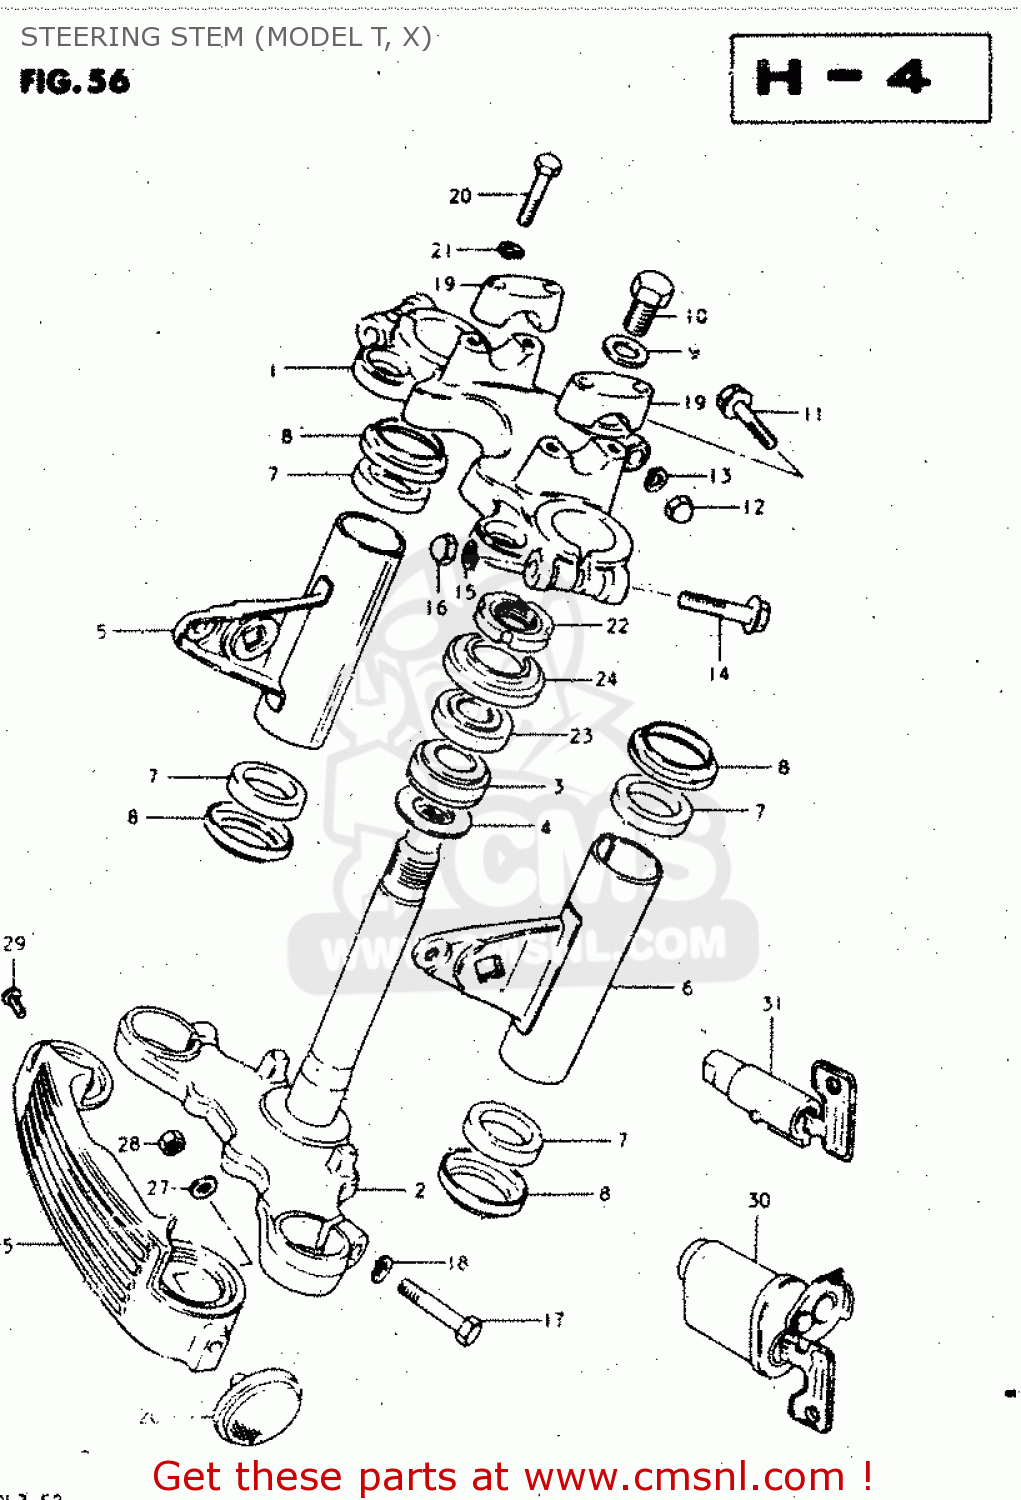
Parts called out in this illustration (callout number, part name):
1	HEAD,STEERING STEM
2	STEERING STEM SET
3	BEARING
4	WASHER,THRUST
5	BRACKET,HEADLAMP,RIGHT
6	BRACKET,HEADLAMP,LEFT
7	CUSHION,HEADLAMP BRACKET
8	CAP,HEADLAMP BRACKET
9	GASKET
10	BOLT(12X20)
11	BOLT
12	NUT,M8X1.25X12
13	LOCK WASHER
14	BOLT 10X55
15	LOCK WASHER
16	NUT 10MM
17	BOLT 10X40
18	LOCK WASHER
19	HOLDER,HANDLE UPR
20	BOLT
21	LOCK WASHER
22	NUT,STEERING STEM(25X44X10)
23	TAPER,ROLLER BEARING
24	DUST SEAL,STEERING,UPPER
25	COVER,FRONT FORK
26	REFLEX REFLECTOR,RR
27	WASHER
28	NUT
29	SCREW
30	LOCK ASSY, STEERING (NEIMAN TYPE EXECUTE
31	LOCK ASSEMBLY,STEERING (NEI
